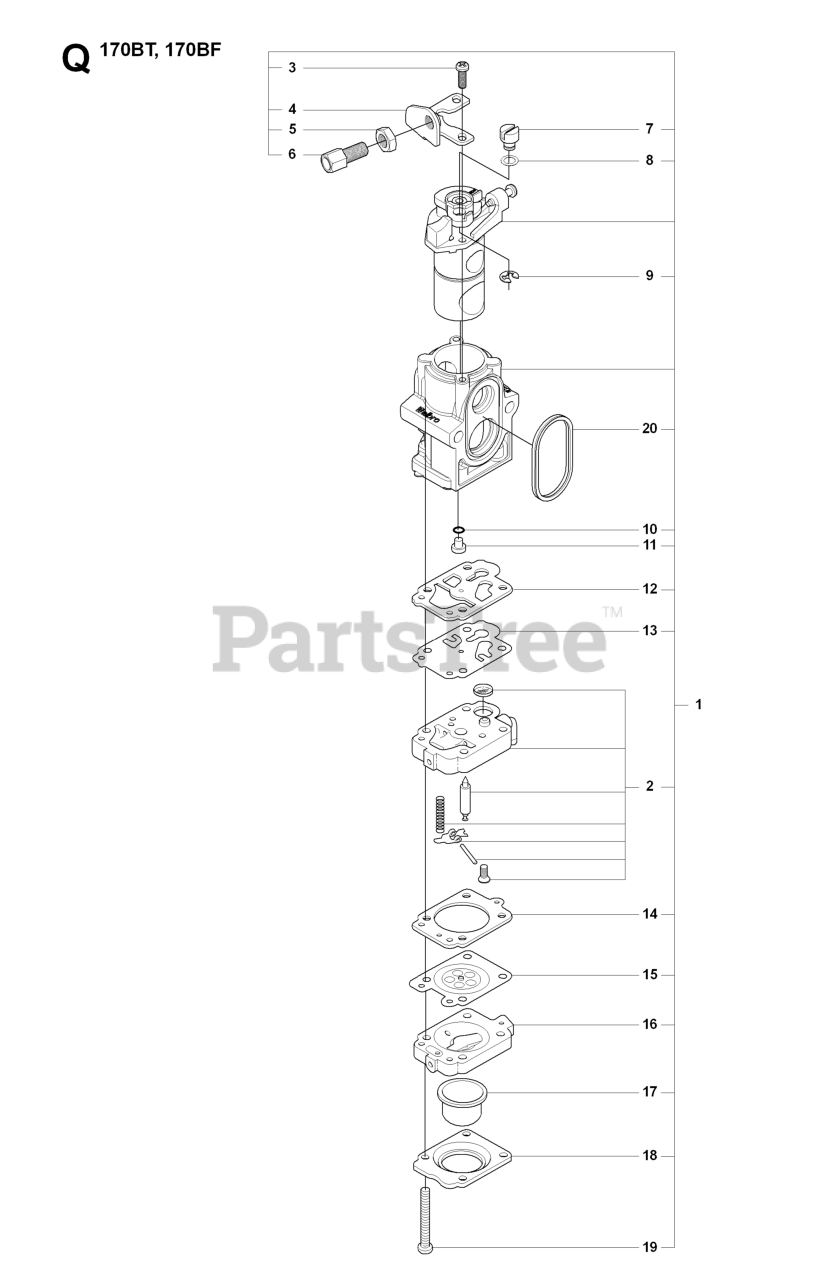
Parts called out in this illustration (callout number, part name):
1	CARB
2	BODY-A-PUMP
5	NUT
6	ADJUSTER
